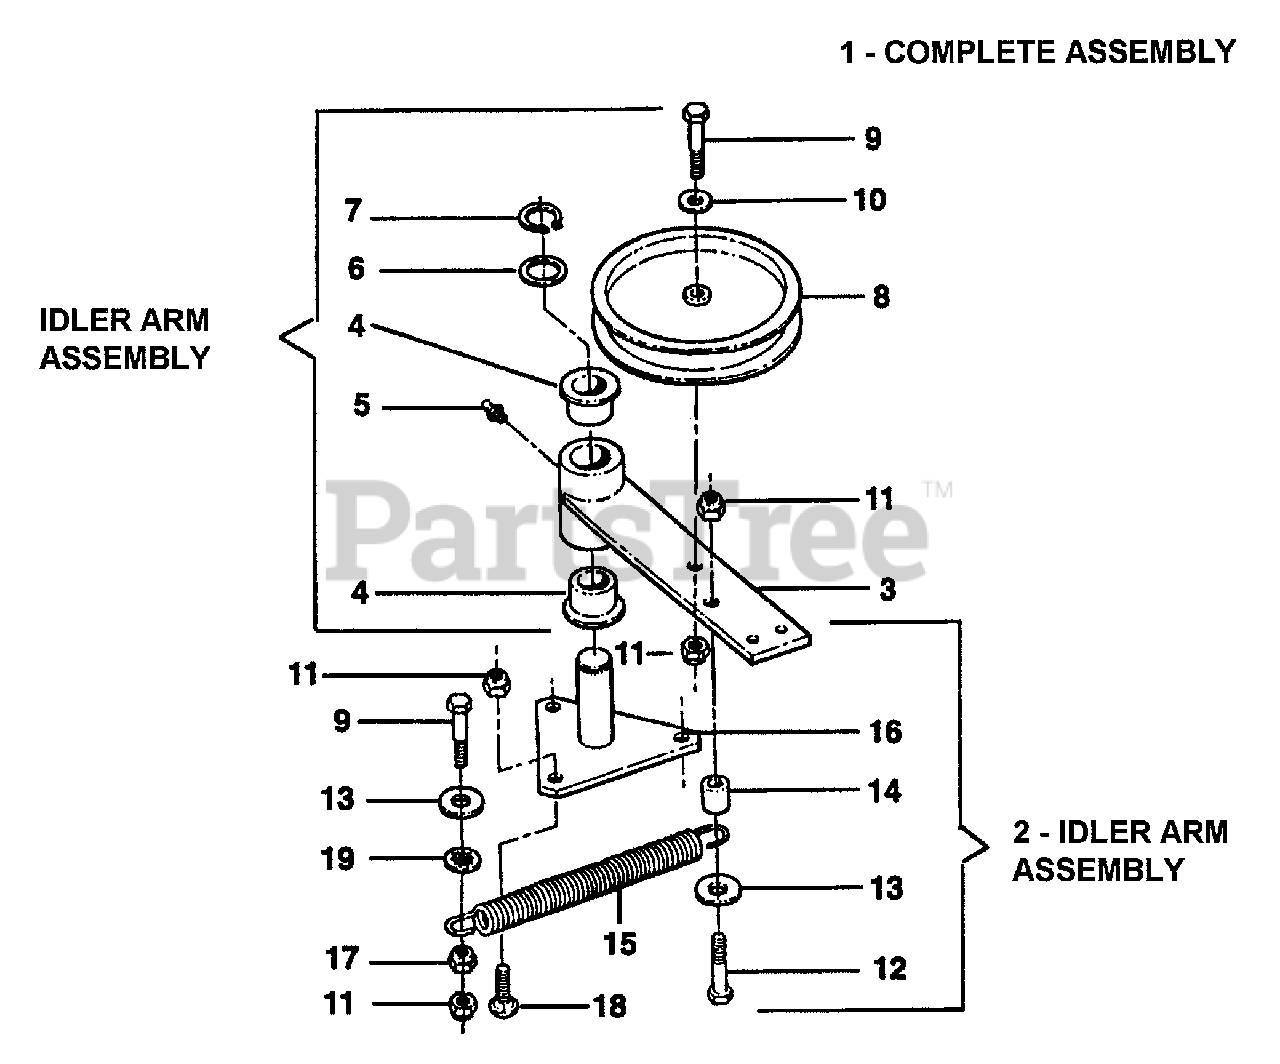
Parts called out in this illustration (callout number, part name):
1	ASSEMBLY, Spring-Loaded Idler Group
2	ASSEMBLY, Idler Arm
3	ARM, Idler (Weldment)
4	BUSHING
5	FITTING, 1/4-28 Straight
6	WASHER, 1.031 x 1.25 x .03" Flat
7	E-RING, 1"
8	PULLEY, 5 1/2" O.D.
9	BOLT, 3/8-16 X 2, GD5, CZ
10	WASHER, 3/8" USS
11	NUT, 3/8-16 HEX NYLON LOCK
12	SCREW, 3/8-16 x 1 3/4" Hex Head Cap, Grade 5
13	WASHER, .406 x 1.5 x .120" (YZ)
14	SPACER, .50 I.D. x .75 O.D. x .83"
15	SPRING, Extension
16	PIVOT, Idler (Weldment)
17	NUT, 3/8-16 HEX SERRATED FLANGE
18	BOLT, 3/8-16 x 1" Carriage
19	RETAINER, 3/8" Bolt
